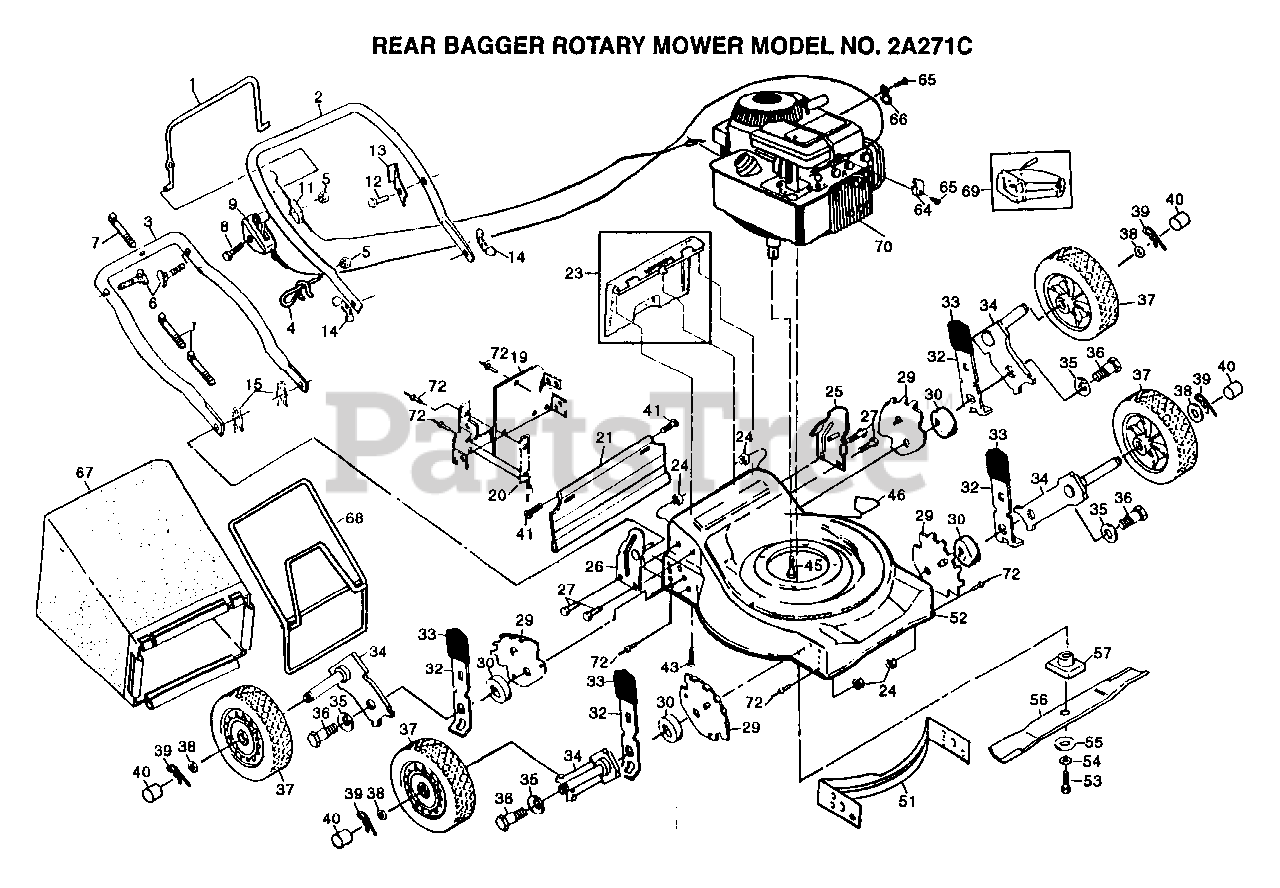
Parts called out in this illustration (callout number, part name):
1	CONTROL BAR
4	ROPE GUIDE
6	BOLT.HANDLE.LM
8	SCREW.HXHD.WASH.
9	CONTROL THROTTLE
11	"CABLE,ENG ZONE CO"
12	TAPPING SCREW
13	"BRKT,UPSTOP"
14	"NUT,WING PM"
15	HAIRPIN COTTER
19	PLATE.BACK.20RD
21	SKIRT.PUSH.20RD
23	"KIT, REAR DOOR PM"
24	LOCKNUT PM
27	SCREW
29	BRACKET.WHL.ADJ.9
32	SPRING SELECTOR
33	KNOB PM
34	AXLE ARM
35	"WASHER, BELLEVIL."
36	BOLT SHLD 3/8-16
37	WHEEL.ASM
38	WASHER
39	RETAINER CLIP PM
40	HUB CAP-PLASTIC
41	HINGE SCREW
43	SCREW
45	SCREW
46	DECAL HYT
52	KIT.HSG.20RD
53	SCREW
54	LOCKWASHER
55	"WASHER,HARDEN"
56	BLADE.STAND.20INC
57	BLADE ADAPTOR
64	CABLE CLAMP
65	SCREW PM
66	GUIDE CLIP PM
67	GRASS BAG
68	CATCHER FRAME
72	BLIND RIVET
